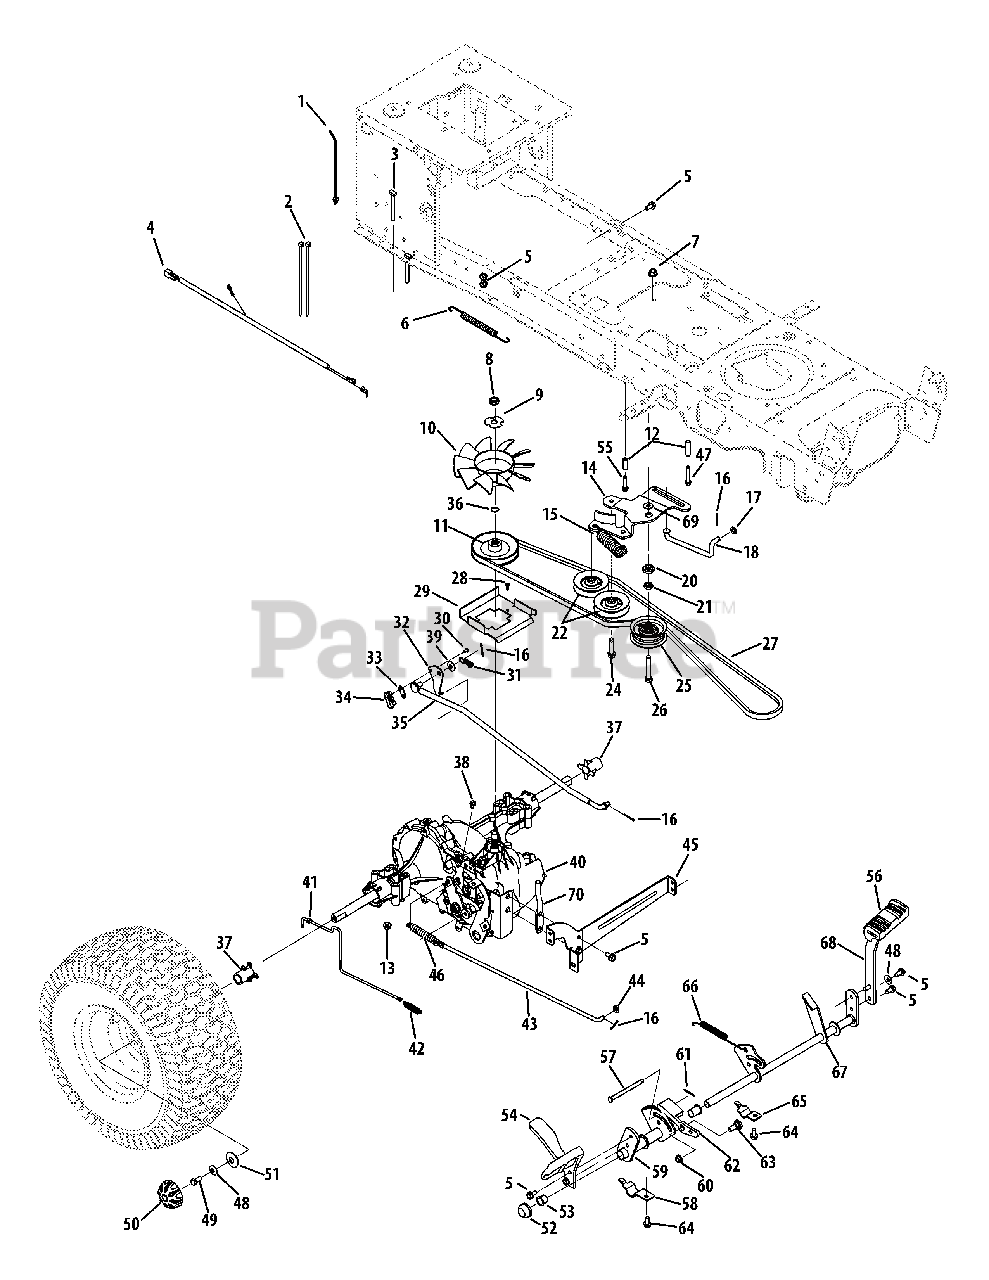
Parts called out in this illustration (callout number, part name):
1	Cable Tie, 7.5
2	Cable Tie, 3/16 x .05 x 7.4
3	Hex Bolt 5/16-18 x 2.75
4	Jumper Harness
5	S-Tapp Scr 5/16-18 x .75
6	Extension Spring .50 dia. x 12.6
7	Flange Locknut 3/8-16 Gr. F
8	Jam Locknut 1/2-10
9	Lockwasher
10	Hydro Fan
11	Input Pulley
12	Spacer, .260 x .372 x 1.420
13	Flange Locknut 5/16-18 Gr. F, Nylon
14	Idler Bracket
15	Extension Spring .59 x 4.0
16	Cotter Pin 3/32 dia x 1.00 Lg.
17	Flat Washer .330 x .630 x .0635
18	Pedal Transmission By pass Rod
20	Shoulder Spacer 1.375 x .38 x .183
21	Hex Jam Nut 7/16-20
22	Idler Pulley
24	Hex L-Wash HD Scr 3/8-16 x 1.5
25	Idler Pulley, Flat 2.75 OD
26	Hex Bolt 3/8-16 x 2.25" Lg.
27	V-Belt
28	Truss Mach B-Tapp Scr #10 X .50
29	Belt Disengage Support
30	Hex Washer Screw #8-18 x .50
31	Extension Spring 3/8 x 1.44
32	Switch Actuator Bracket
33	Insulator Nut Plate
34	Short Spring Switch
35	Hydro Control Rod
36	Wire Ring
37	Sleeve 0.765 x 1.5
38	Hex Wash HD Tapp Scr 1/4-20 x .375
39	Flat Washer .406 ID x .812 OD x .134
40	Hydro Transmission
41	Hydro Bypass Rod
42	Extension Spring .47 OD x 2.03 Lg.
43	Brake Rod
44	Flat Washer .312 ID x .75 OD
45	Hydro Mount Bracket
46	Extension Spring .59 x 4.0
47	Hex Washer Hd. TT Screw 1/4-20 x 1.75
48	Cupped Washer .345 ID x .88 OD x .060
49	Hex L-Bolt 5/16-24 x .75 Gr. 5
50	Hub Cap
51	Flat Washer .350 x 1.59 x .062
52	Push Cap 5/8" Dia Rod
53	Nyliner Flanged Brg.
54	Control Pedal
55	Hex Washer Hd. TT Screw 1/4-20 x 1.625
56	Brake Pedal Pad
57	Clevis Pin 5/16 x 3.985
58	Transmission Rod Support Strap
59	Hydro Pedal Brkt. Assembly
60	Flange Lock-Nut 3/8-16 Gr. F Nylon
61	Bow-Tie Cotter Pin
62	Cruise Latch
63	Shoulder Screw .500 x .25
64	Self-tapping Screw 5/16-18 x .625
65	Brake Shaft Support Strap
66	Extension Spring .63 x 4.95
67	Brake Control Assembly
68	Brake Pedal Bracket
69	Flat Washer .385 ID x 1.0 x .030
70	Belt Keeper Rod
